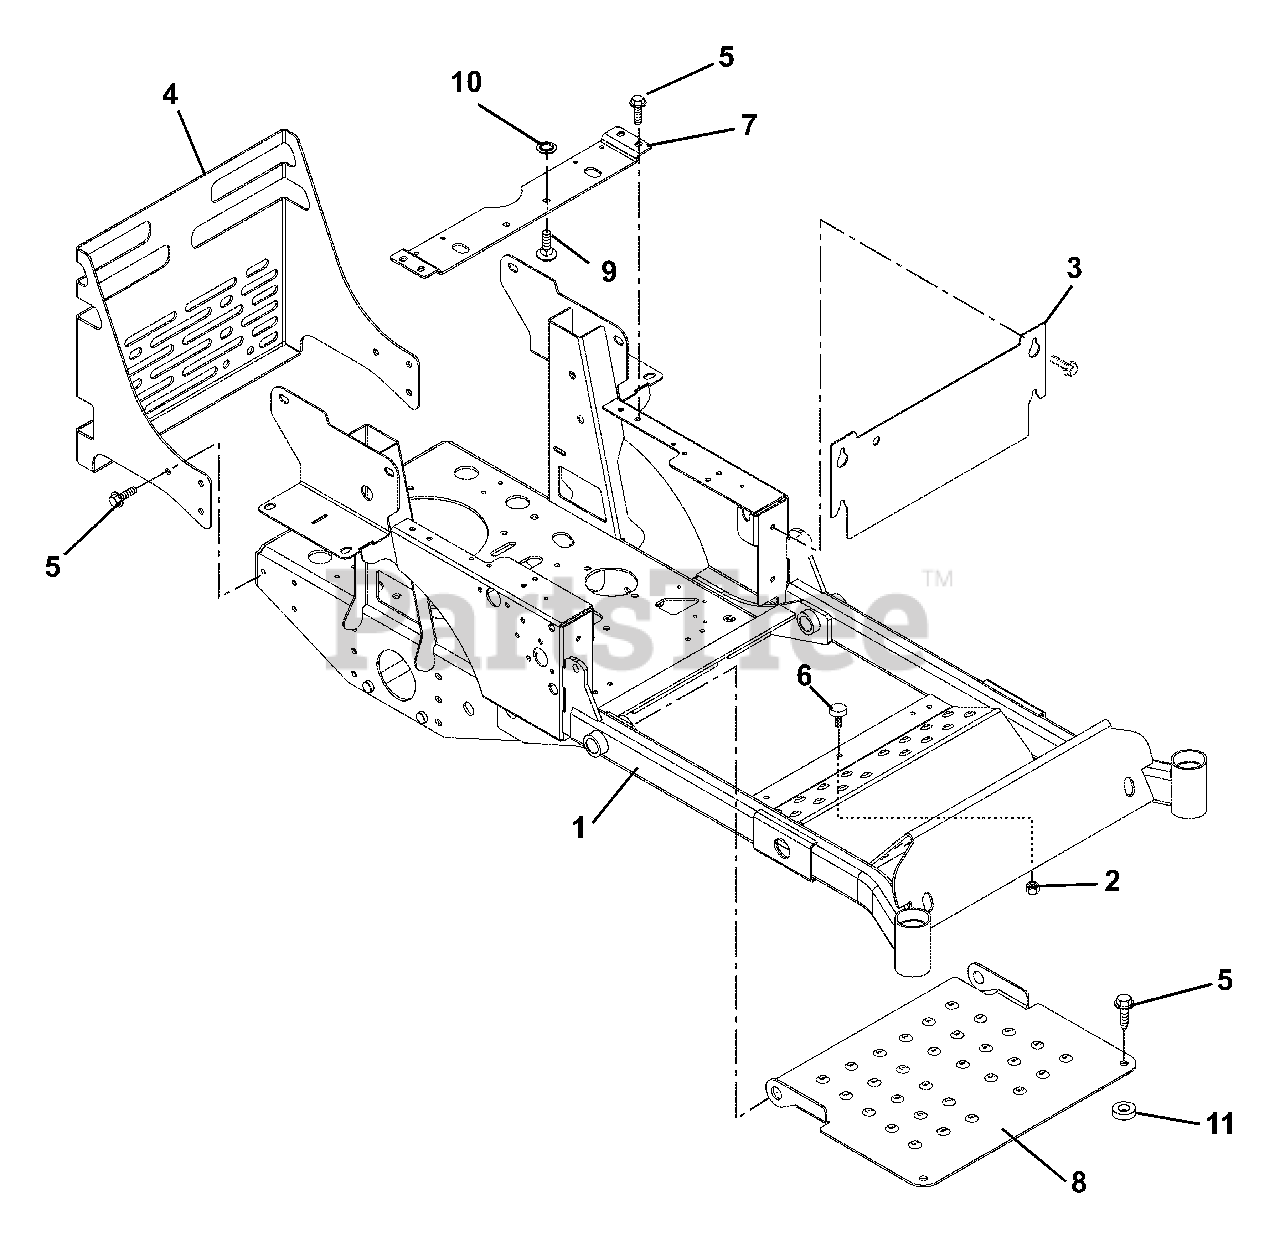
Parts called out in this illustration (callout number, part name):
1	WMT, FRAME COMPACT-Z
2	@NUT-SPNLK-FLG .312-18 YWZC
3	PANEL, ACCESS
4	BUMPER, REAR
5	@SCR-TAP .38-16X.50 HWH TR YWZ
6	BUMPER, RUBBER
7	SUPPORT, SEAT
8	PANEL, INSPECTION
9	@BLT-RHDSSQNK .31-18X.75 G5YZ
10	NUT-PUSH .312
11	SPACER .380X.750X.236
